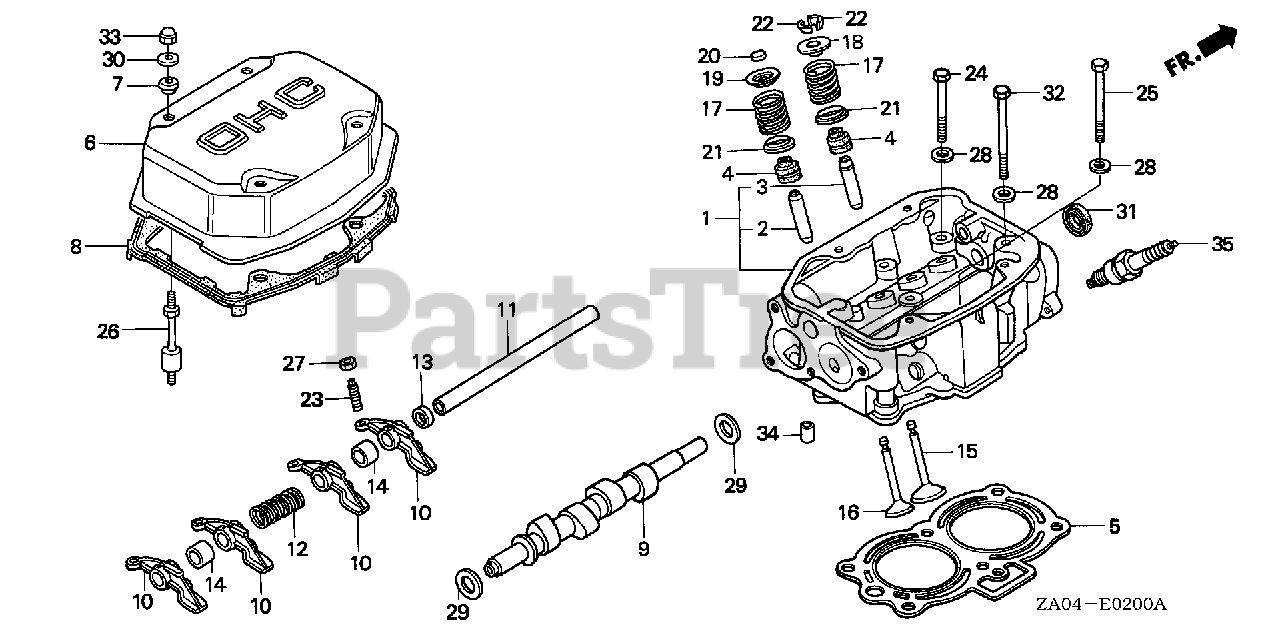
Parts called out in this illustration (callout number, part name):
1	CYLINDER HEAD
2	GUIDE, EX. VALVE
3	GUIDE, VALVE (OS)
4	SEAL, VALVE STEM
5	GASKET, CYLINDER HEAD
6	COVER, CYLINDER HEAD
7	WASHER, HEAD COVER
8	GASKET, HEAD COVER
9	CAMSHAFT
10	ARM, VALVE ROCKER
11	SHAFT, VALVE ROCKER ARM
12	SPRING, VALVE ROCKER ARM
13	COLLAR A, VALVE ROCKER ARM
14	COLLAR B, VALVE ROCKER ARM
15	VALVE, IN.
16	VALVE, EX.
17	SPRING, VALVE
18	RETAINER, VALVE SPRING
19	RETAINER, VALVE SPRING
20	ROTATOR, VALVE
21	SEAT, VALVE SPRING
22	COTTER, VALVE
23	SCREW, TAPPET ADJ.
24	BOLT, HEAD (8X70)
25	BOLT, HEX. (8X55)
26	BOLT, SPECIAL STUD
27	NUT, TAPPET ADJ.
28	WASHER, HEAD (8MM)
29	WASHER, THRUST (16MM)
30	WASHER (6X17)
31	OIL SEAL (16X28X6)
32	BOLT, HEX. (8X100)
33	NUT, CAP (6MM)
34	PIN A, DOWEL (10X16)
35	SPARK PLUG (W16FPR) (DENSO)
35	SPARK PLUG (BPR5HS) (NGK)
35	SPARK PLUG (BPR6HS) (NGK)
35	SPARK PLUG (W20FPR) (DENSO)
35	SPARK PLUG (BPR7HS) (NGK)
